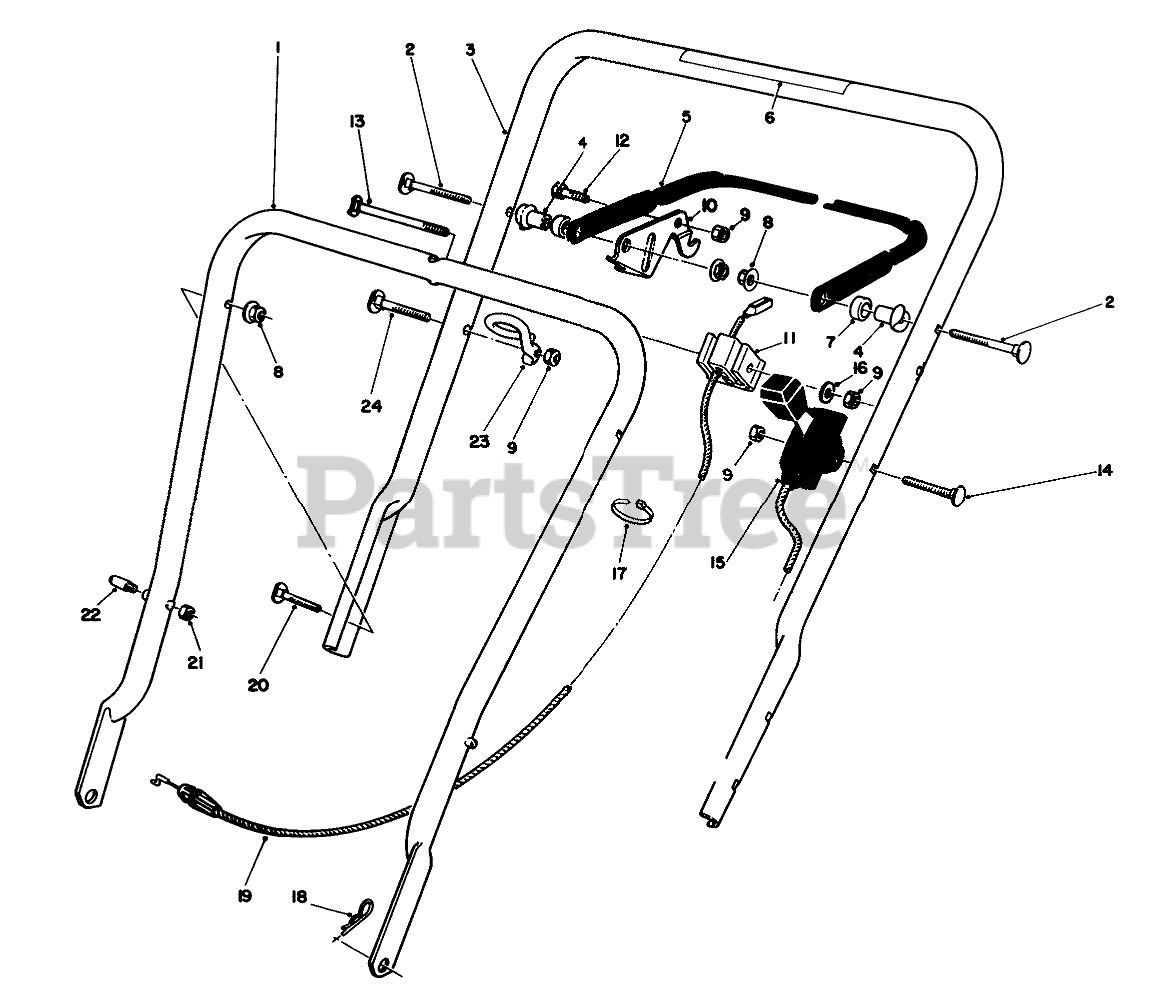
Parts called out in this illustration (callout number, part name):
1	LOWER HANDLE ASM
2	5/16-18 X 2 HNDLE SCREW
3	Handle-Upper (Incl. Ref. #6)
4	SPACER-SUPPORT
5	Bar-Control
6	WARNING DECAL
7	SPACER-NYLON
8	NUT-LOCK, NI
9	NUT-LOCK, NI
10	LEVER-CONTROL
11	SUPPORT-CABLE
12	SCREW-HH
13	HANDLE SCREW
14	SCREW-HANDLE
15	THROTTLE CONTROL
16	WASHER-FLAT
17	TIE-CABLE
18	PIN-COTTER, HAIR
19	OBS BRAKE CONTROL
20	SCREW
21	NUT-LOCK, NI
22	HANDLE PIN
23	Guide
24	HANDLE SCREW
